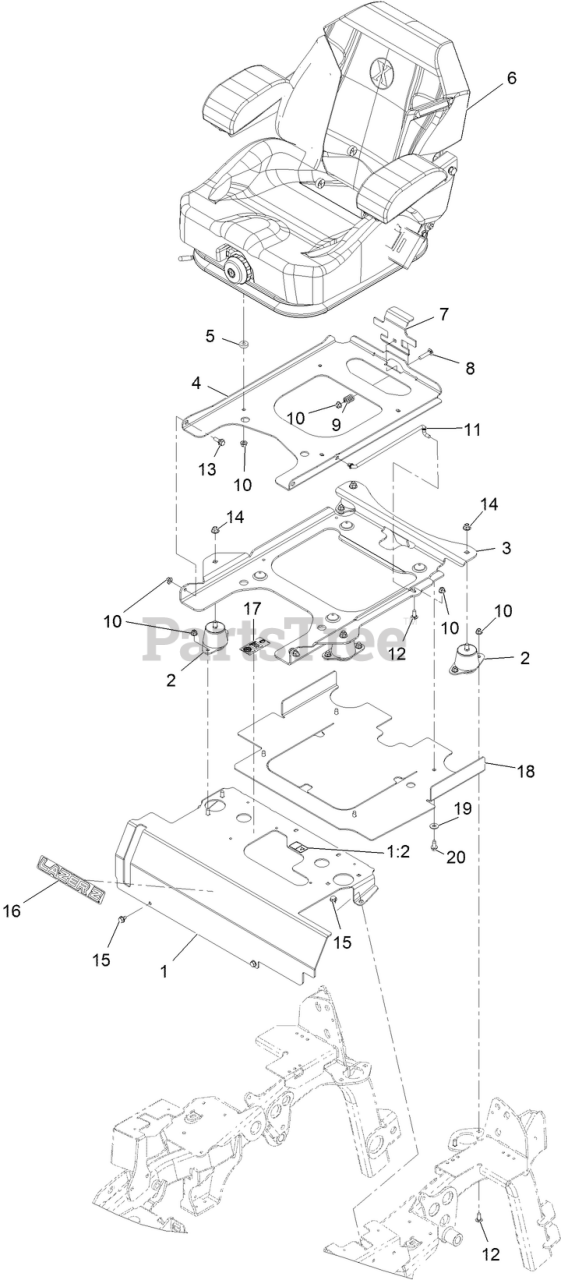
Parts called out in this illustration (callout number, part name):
1	MOUNT-SEAT W/DECALS
1:2	DECAL-WARNING
2	ISOLATOR-SEAT
3	Plate,Tilt Seat Support
4	PLATE-FRAME, SEAT
6	ASM-SUSPENSION SEAT, EXMARK
7	PLATE, SEAT LATCH
8	BOLT-CARR
9	SPRING-COMPRESSION
10	NUT-HF, NI
11	ROD-PROP
12	SCREW-CARR
13	SCREW-SHOULDER
14	NUT-HF, NI
16	DECAL, LAZER MODEL
17	DECAL-TRANS FLUID
18	SHIELD-HEAT
19	WASHER-FLAT
20	Screw-HWH 5/16-18 X 3/4 Tf
